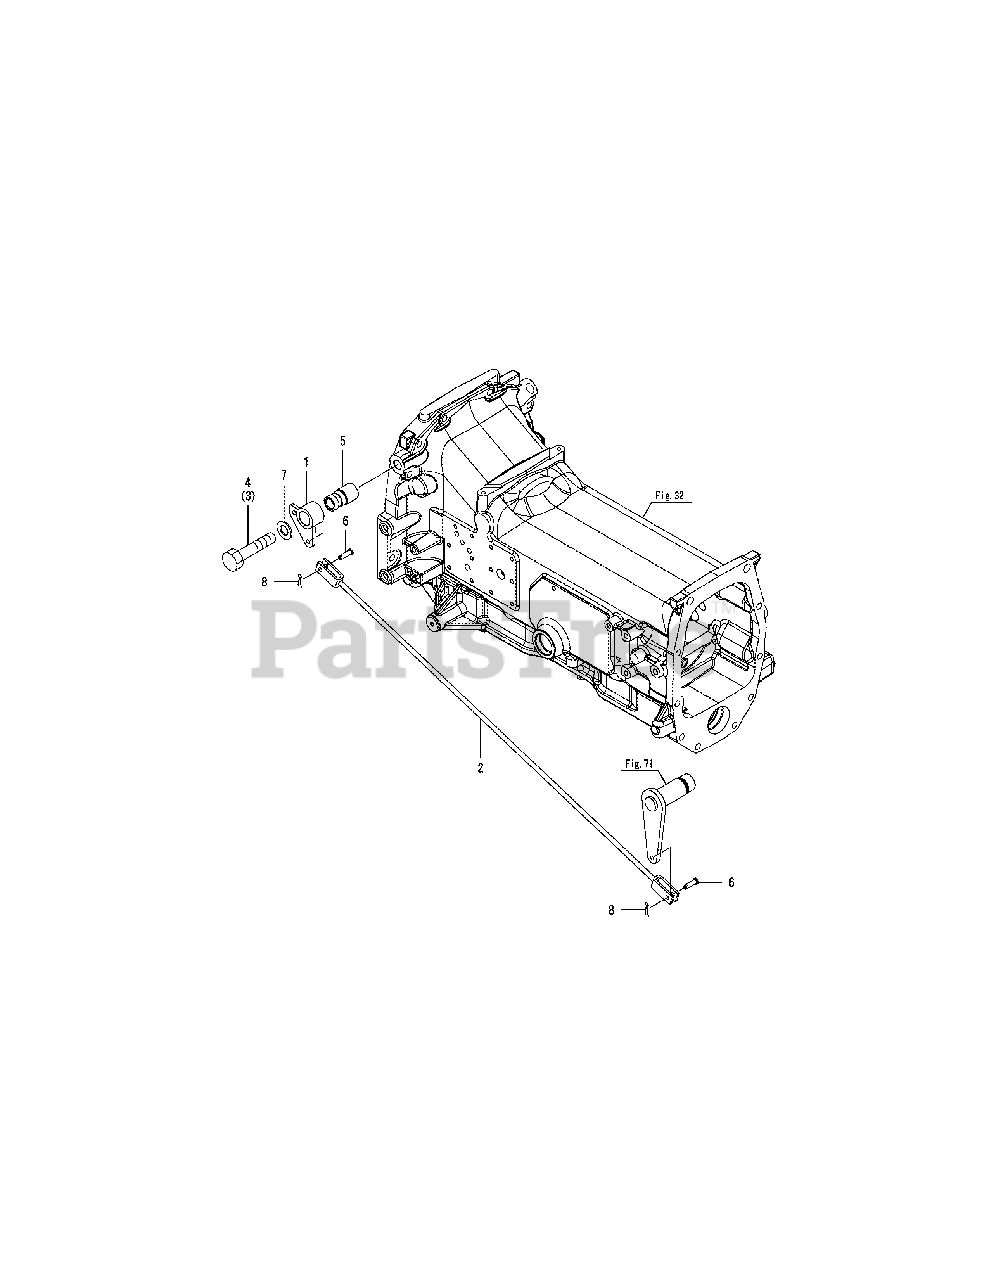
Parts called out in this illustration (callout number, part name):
2	ROD, BRAKE ASSY
3	BOLT, M20X95 RH
4	BOLT, M20X95 LH
5	SPACER, 20X29X61
8	COTTER PIN 2.5X30
